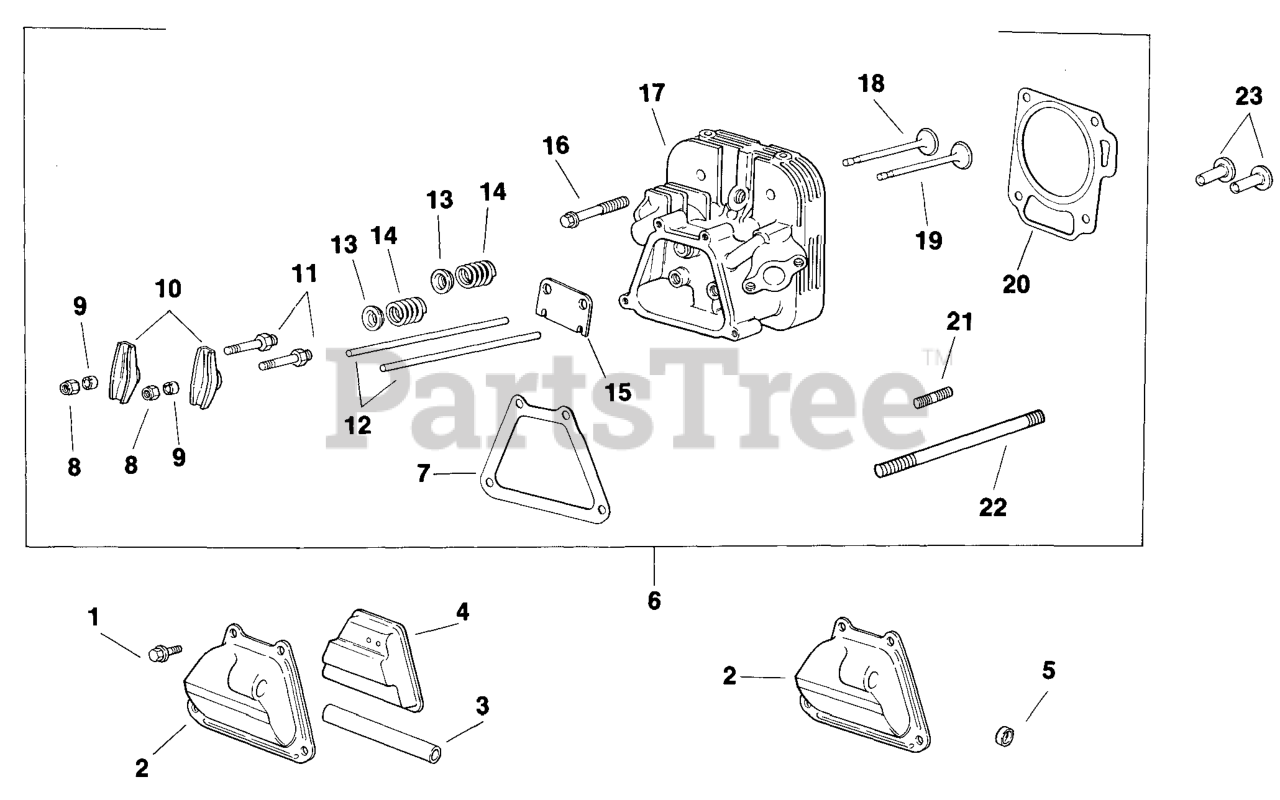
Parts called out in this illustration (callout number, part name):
1	SCREW,FLG THD FRM M6X1.0X20-(#25086396S)
6	KIT, CYLINDER HEAD
7	GASKET, ROCKER COVER
10	ARM - DISCONTINUED
13	RETAINER, VALVE SPRING
16	SCREW, FLG M8X1.25X54
17	HEAD, CYLINDER
18	VALVE, EXHAUST
19	VALVE, INTAKE
20	GASKET, CYL HEAD
21	STUD, EXHAUST-USE 25 072 24-S
22	STUD,M6X1.0X92
1501602-S	VALVE, EXHAUST
1501702-S	VALVE, INTAKE
